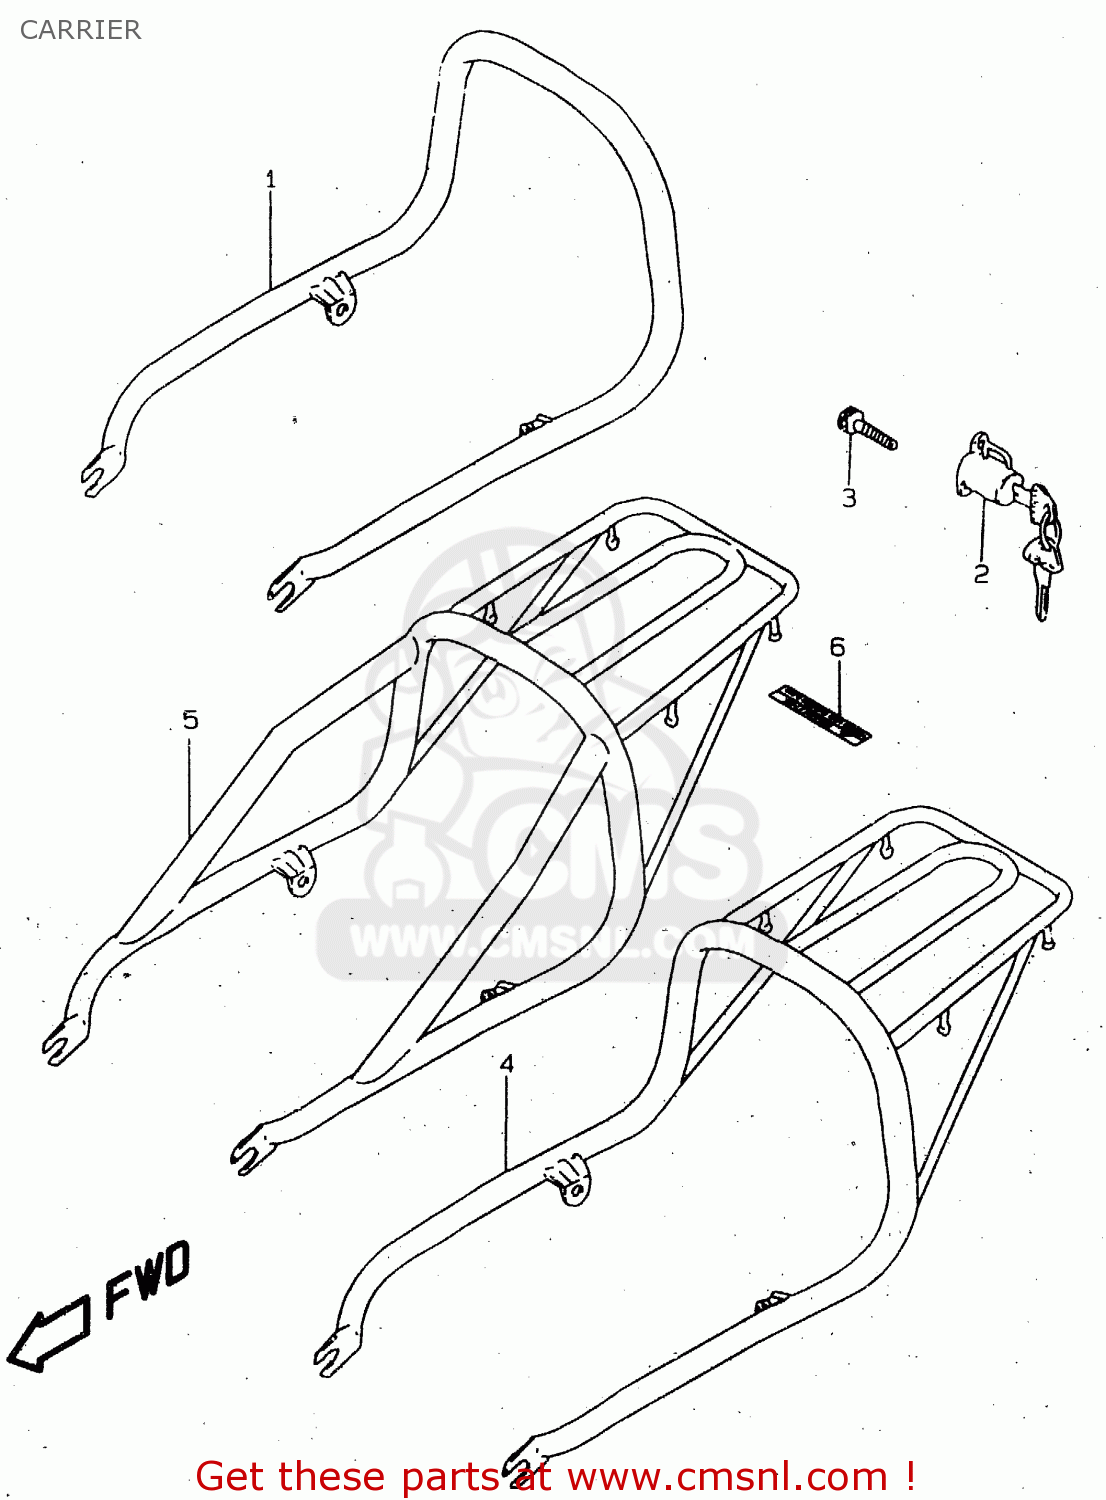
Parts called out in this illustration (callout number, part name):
1	HANDLE,PILLION RIDER
2	LOCK SET,HELMET
3	SCREW(6X12)
4	CARRIER
5	CARRIER SET,SUPPORT
6	LABEL,RR CARRIER
